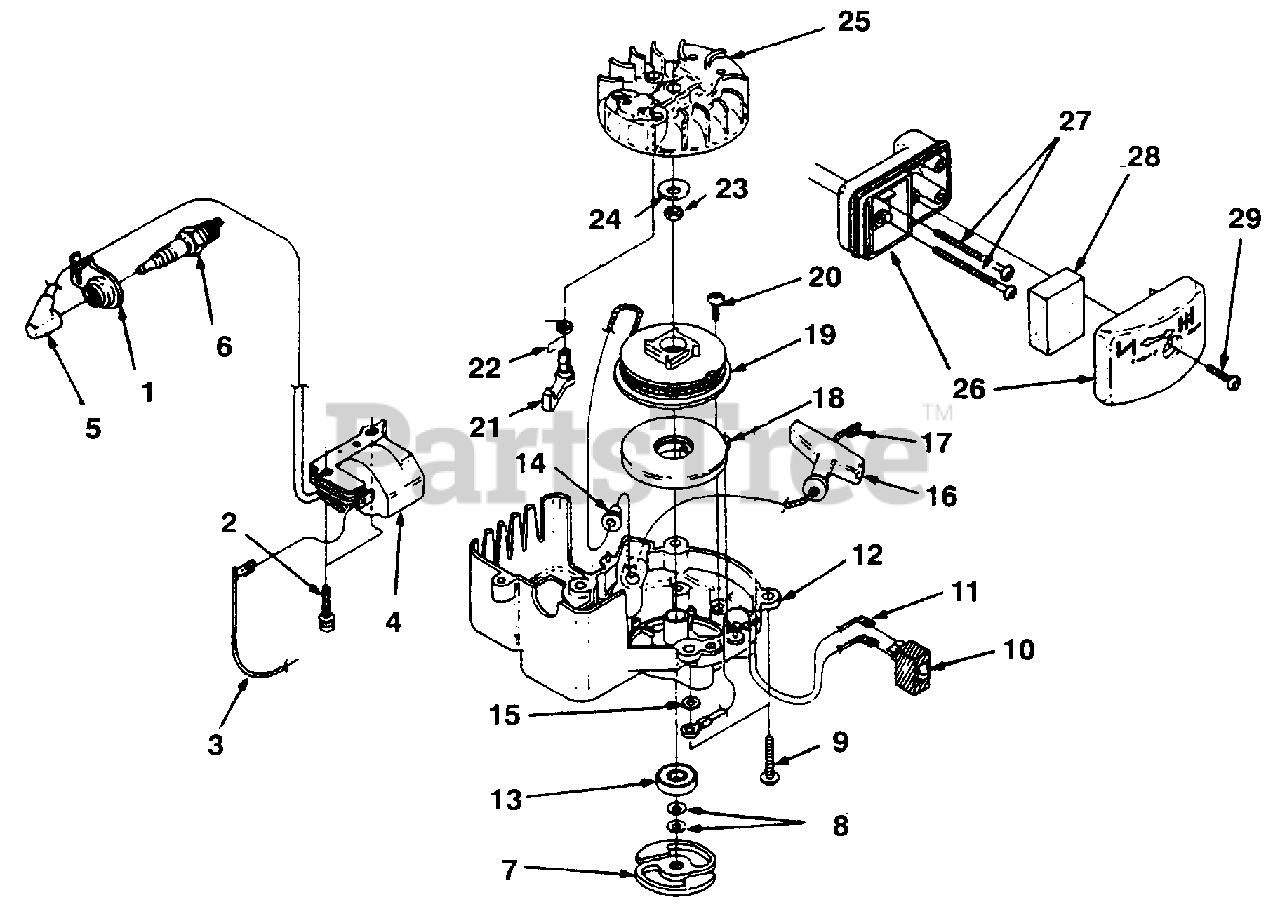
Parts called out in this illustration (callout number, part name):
1	SHIELD-Spark Plug
2	SCREW-Thread Form. (8-32 X 1")
3	LEAD-Electrical
4	MODULE-Ignition
5	SPARK PLUG BOOT KIT
6	SPARK PLUG (DJ-7Y)
7	CLUTCH "S"
8	WASHER-Belleville
9	SCREW-Taptite (10-24 X 3/4")
10	SWITCH
10	SWITCH (HT-17I, HT-19I, HT-21I)
11	LEAD-Ground
12	HOUSING-Engine & Pulley
13	BEARING-Ball
14	BUSHING-Starter
15	WASHER-Flat (#10)
16	GRIP-Starter Rope
17	ROPE-Starter (42")
18	SPRING & CONTAINER
19	PULLEY-Starter
20	SCREW-Thread Form. (#10 X 1/2")
21	PAWL-Starter
22	SPRING-Torsion
23	NUT-Hex (7/16-20)
24	WASHER-Conical
25	ROTOR
26	AIR FILTER HOUSING
27	SCREW-Machine (10-24 X 2 1/4")
28	FILTER-Air
29	SCREW-Thread Form. (#8 X .750)
